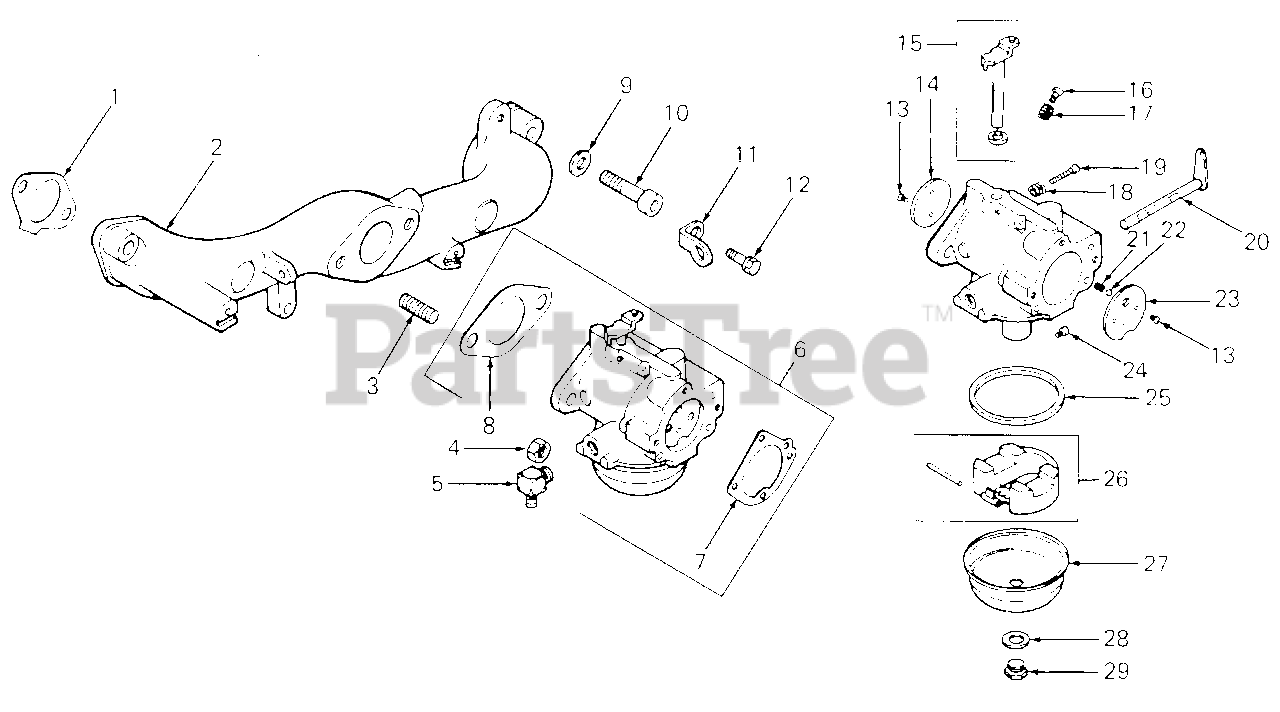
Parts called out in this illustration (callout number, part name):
1	Gasket, Manifold
2	Manifold, Intake
3	Stud, 5/16-18 X 1
4	Nut, Hex, 5/16-18
5	Connector, 90 Hose
6	Carburetor Assy w/ Gasket
7	Gasket, Air Intake Elbow
8	Gasket, Carburetor
9	Washer, Plain, 5/16
10	Screw, Hex Socket, 5/16-18 X 1-1/4
11	Strap, Hanging
12	Screw, Hex Wash, 1/4-20 X 5/8
13	Screw, Throttle & Choke Plate
14	Plate, Throttle
15	Shaft, Throttle w/ Lever & Seal
16	Needle, Idle Fuel Adj
17	Spring, Idle Fuel
18	Spring, Idle Speed
19	Screw, Idle Speed Adj
20	Lever, Choke
21	Spring, Choke Friction
22	Ball, Choke Friction
23	Plate, Choke
25	Gasket, Bowl
28	Gasket, Bowl Retainer Screw
29	Screw, Bowl Retainer
